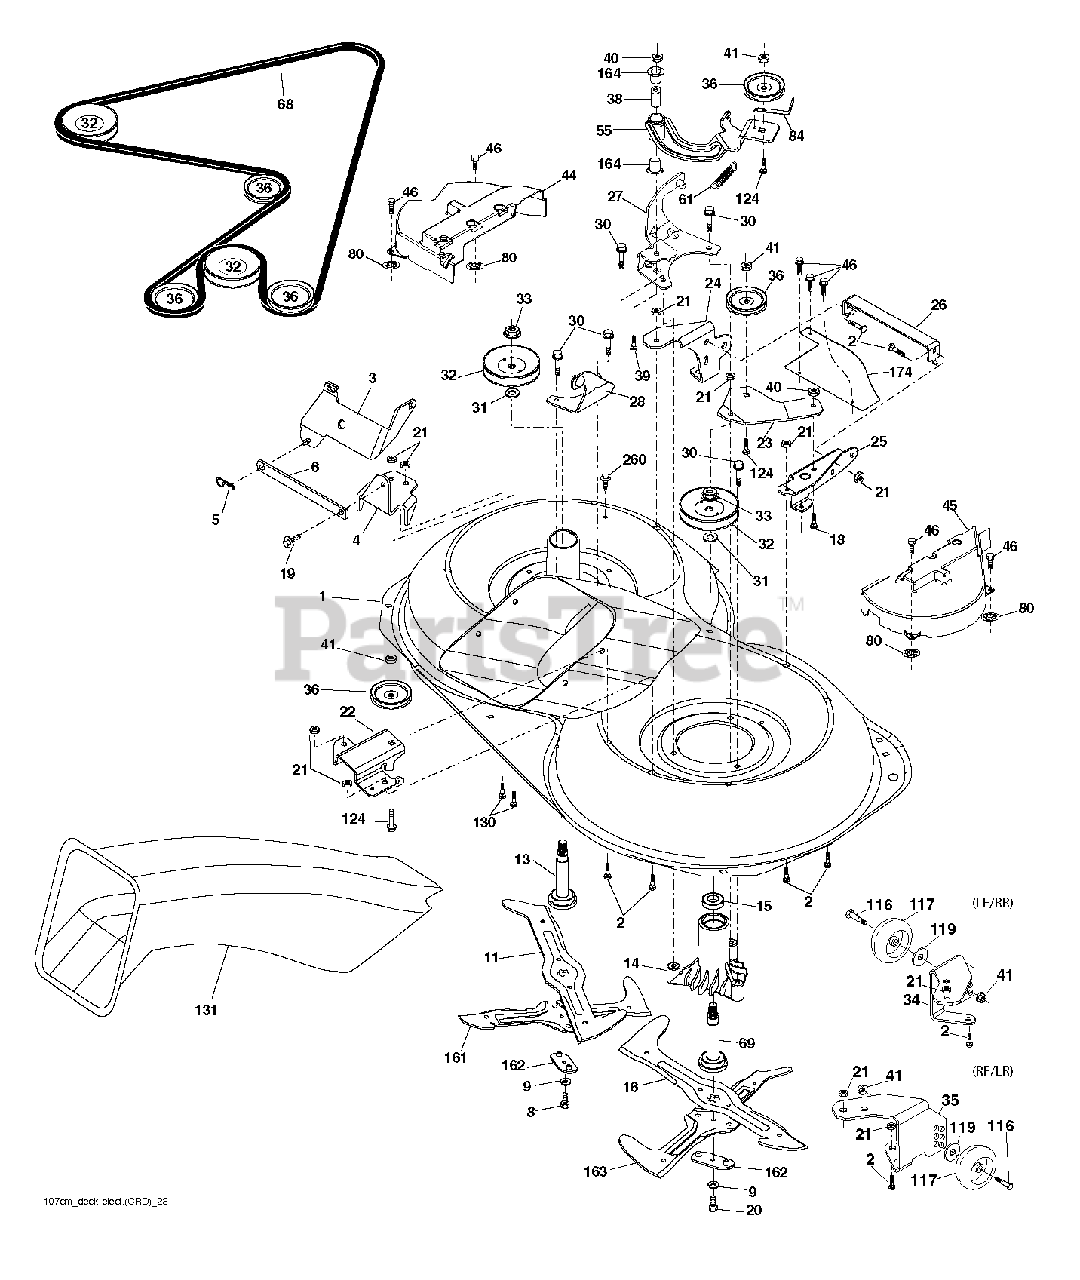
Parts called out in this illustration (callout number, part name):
2	BOLT 5/16-18 X3/4 ZN/YEL GR 5
3	BRACKET.ASM.BAR.SWAY.CHASS
5	Retainer Spring
6	BAR.SWAY.92.CRD
8	BOLT.3/8-24X1.25 GR8
9	LOCKWASHER
11	BLADE.3N1.LH.CRD
13	SHAFT ASM VENT
14	HOUSING.MANDREL.VENTED (MACHD)
16	BLADE.3N1.RH.CRD
19	BOLT SHD 5/16-18
20	BOLT.3/8-24X1.25GR8. LHTHRD
21	LOCKNUT
22	BRACKET.IDLER.RR.107.CRD
24	BRACKET
25	BRACKET RF
26	SUPPORT
28	BRACKET
30	SCREW, WASHER HEAD
31	WASHER.SPACER.MANDREL
32	PULLEY.MANDREL.4.80 PD.2006
33	NUT.FLANGE.LOCK.TOP
34	BRACKET
35	BRACKET
36	PULLEY.IDLER.4.25
41	NUT LOCK FLG 3/8-16 UNC
44	COVER.MANDREL.LH.107 CRD.FRENC
45	COVER MANDREL RIGHT
46	SCREW.1/4-20X5/8
55	ARM.IDLER.107.CRD
61	SPRING
68	HEX-BELT 107 MOWER
69	SHAFT.ASM.W/LWR.BRG.RH.THREAD
80	PALNUT 1/4
84	KEEPER, BELT IDLER
116	BOLT.SHOULDER.3/8-16X3-5/8.
117	WHEEL. GUAGE RALLY
119	WASHER
124	BOLT.3/8-16X1.50
130	BOLT.CARR.SQNK.5/16-18UNC.X3/4
131	CHUTE BAGGER
161	ADAPTER ADAPTER.CROSSBLADE.107
162	ADAPTER ADAPTER.CROSSBLADE.107
163	BLADE.CROSS.RH.CRD.107
164	BRNG T
174	PLATE
260	SCREW 3/8-16X1/2
